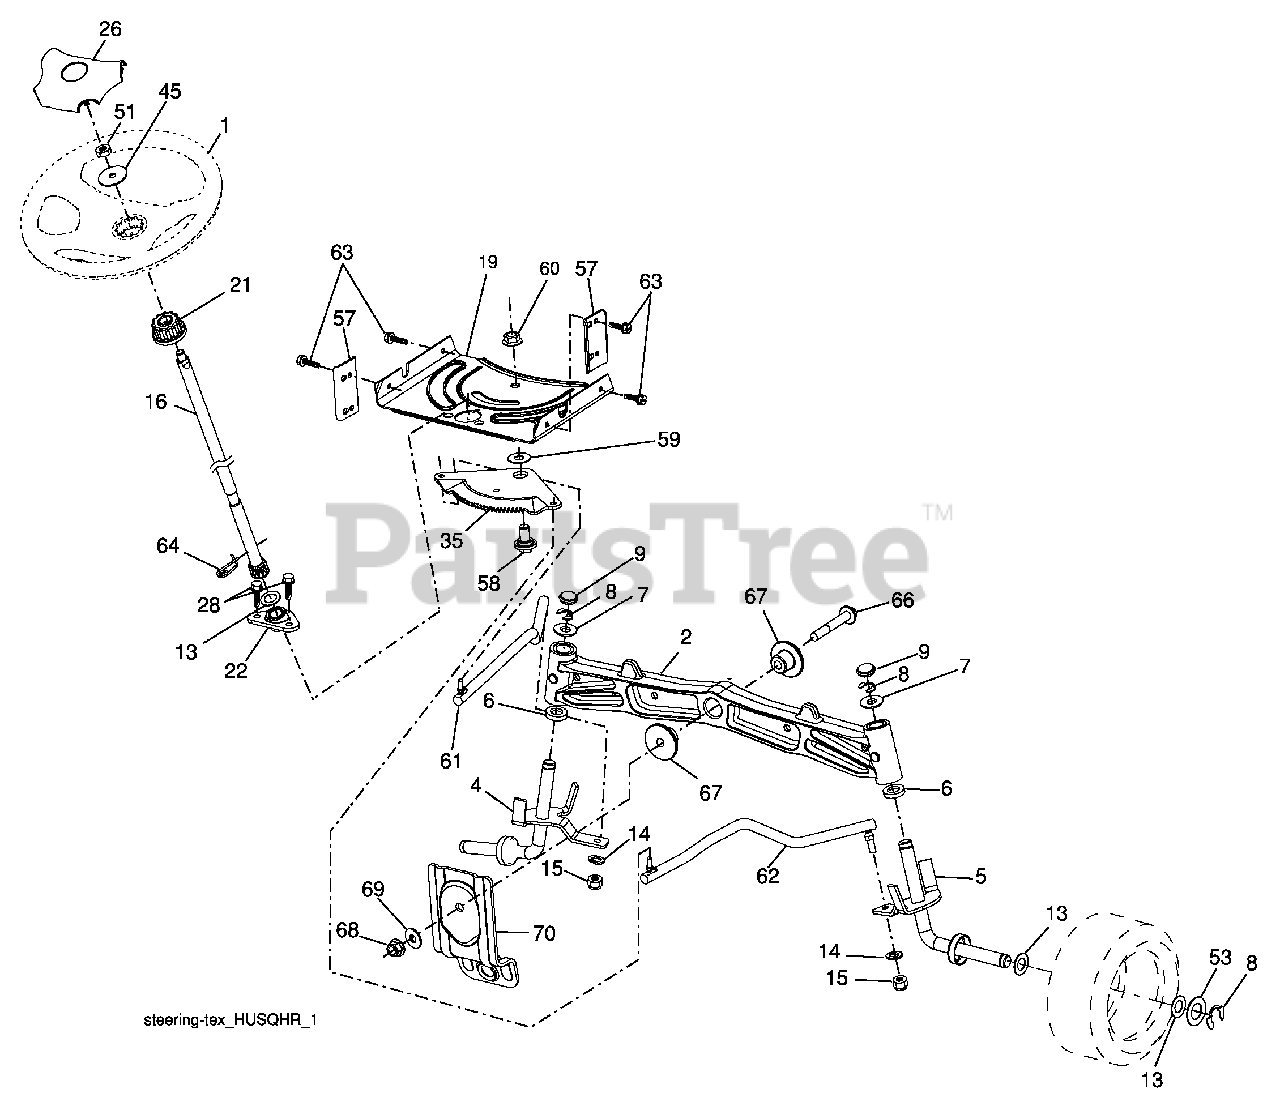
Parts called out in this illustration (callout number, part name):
1	Wheel, Steering
2	Axle Cast Iron
4	Spindle Asm., LH
5	Spindle Asm., RH
6	Washer, Thrust
7	Washer 25/32 x 1-5/8 x 16 Ga.
8	Ring, Klip #T5304-75
9	Cap, Spindle
13	Washer 25/32 x 1-1/4 x 16 Ga.
14	Washer, Lock Hvy Hlcl Spr 3/8
15	Nut, Crown Lock 3/8-24 unf
16	Shaft Steering
19	Plate Steering
21	Adapter, Wheel Steering
22	Steering Support
26	Insert, Wheel Steering
28	Screw 3/8-16 x 3/4
35	Gear, Sector Plate
45	Washer 9/16 ID x 2-3/8 OD 12 Ga.
51	Nut Hex Jam Toplock 1/2-20 unf
53	Washer Hardened .793 x 1.637 x .060
57	Bracket Upstop
58	Bolt Shoulder Sector Pivot CFM
59	Washer Thrust Sector Steering
60	Nut Flange Lock 5/8-11
61	Draglink, LH
62	Draglink, RH
63	Screw 5/16-18 x 3/4
64	Retainer Clip Spring Steering
66	Bolt Hex Fghd 7/16-14 x 3 Serr
67	Bushing PM Front Axle
68	Nut Lock Flange 7/16-14 Gr. 5
69	Washer 1.5 x .505 x .118
70	Bracket Deck Susp. Front
